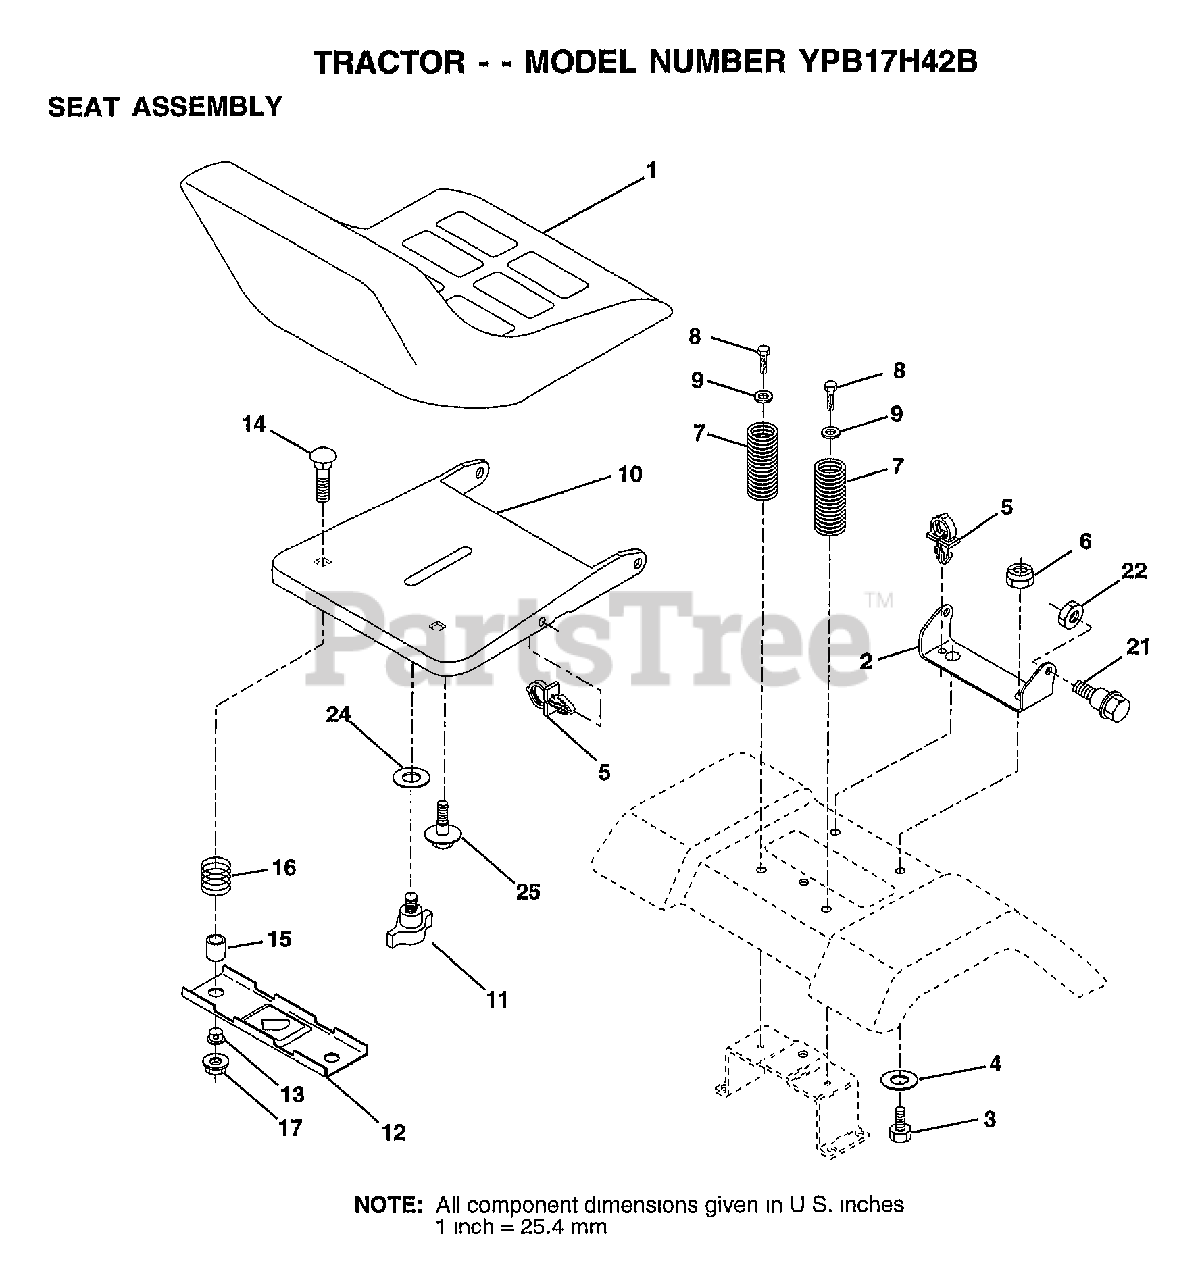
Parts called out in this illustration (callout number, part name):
1	SEAT.2400/1416.BK
2	BRACKET PVT SEAT
3	BOLT
4	WASHER PM
5	CLIP.PUSH-IN.HING
6	NUT
7	SPRING COMPRESSIO
8	SCREW
9	WASHER
10	PAN-SEAT
11	KNOB.SEAT.ADJ.WINGNUT
12	BRKT SWITCH
13	BUSHING
14	BOLT-RD HD SQ NK
15	SPLIT SPACER
16	SPRING
21	"BOLT,SHOULDER"
22	NUT
24	WASHER
25	"BOLT,SHOULDER"
